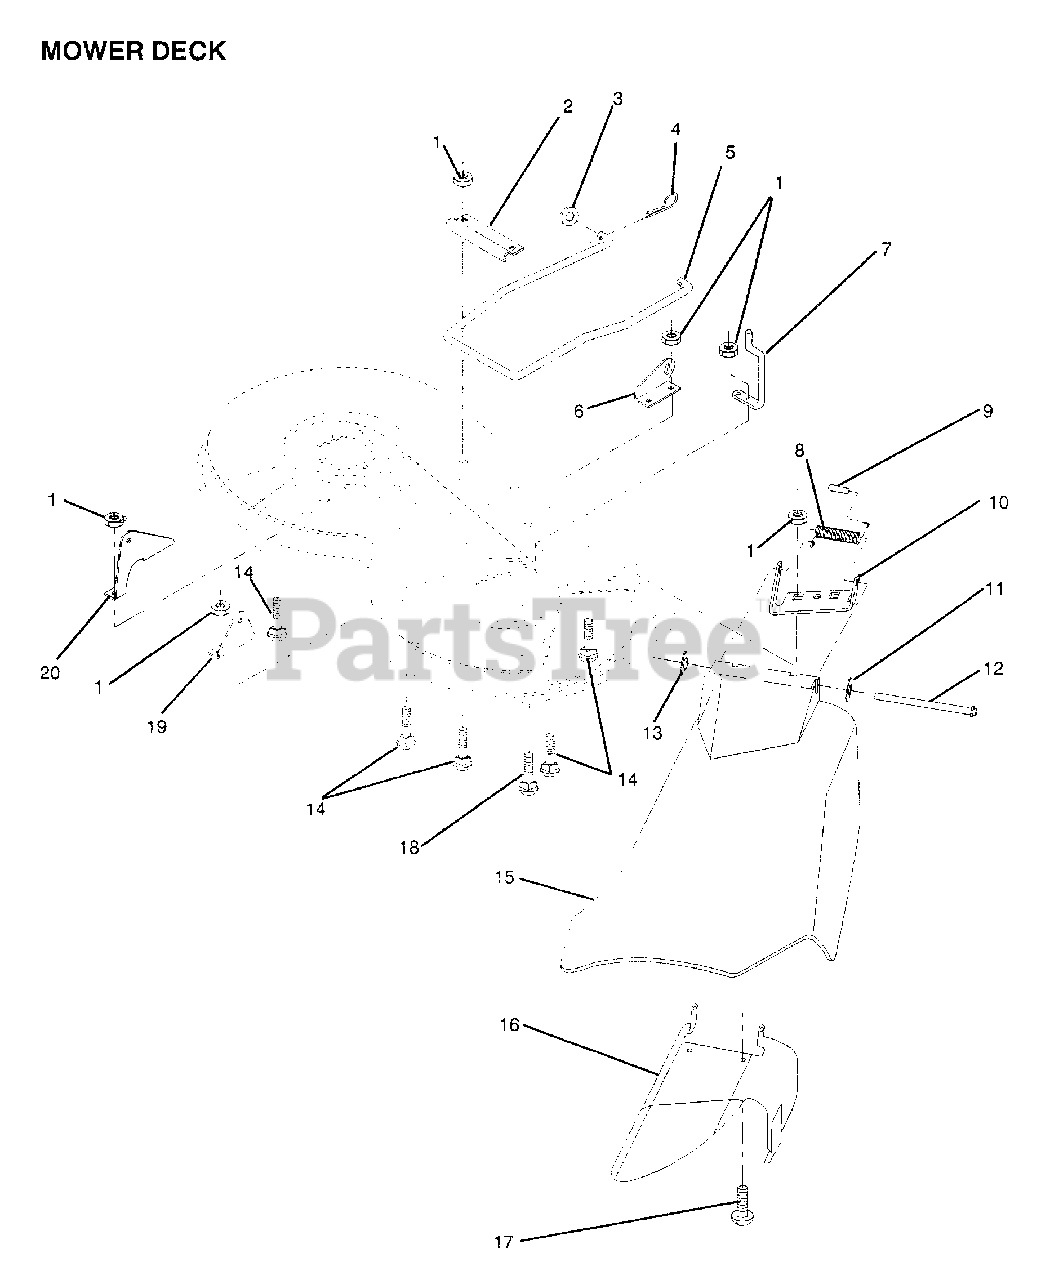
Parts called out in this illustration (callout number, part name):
2	"BRKT,STAB LINK"
4	RETAINER.SPRING
5	STABILIZER MOWER
6	"BRKT,FRT LIFT RH"
7	"GUIDE,FRT MAN RH"
8	SPRING TORSION
9	CAP-SLEEVE LT
11	WASHER
12	HINGE ROD
13	NUT PUSH M
14	BOLT
16	DEFL SUPT ASS'Y
17	SCREW PAN HD
18	BOLT
19	"BRKT,REAR LIFT RH"
20	"BRKT,REAR LIFT LH"
